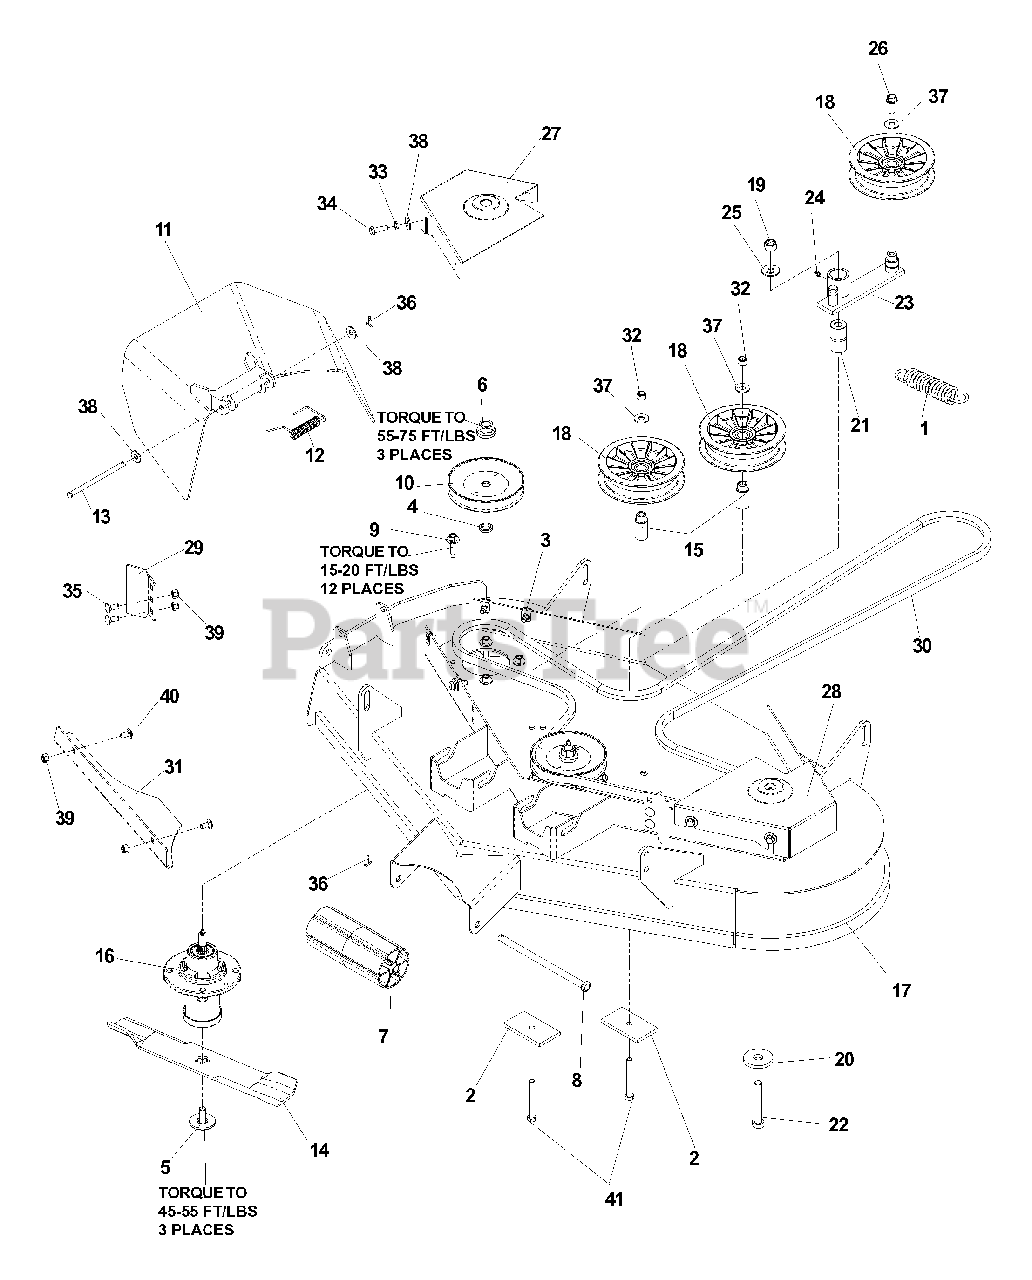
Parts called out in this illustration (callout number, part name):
1	SPRING, EXTENSION
2	PAD
3	NUT, 5/16-18, RETAINER-U TYPE
4	WASHER, .675 X .915 X .155, SPACER
5	BOLT, 7/16, SPEC
6	NUT, 9/16, CENTERLOCK, GR5
7	ROLLER, NOSE
8	ROD, ROLLER, NOSE, NARROW
9	SCREW, 5/16-18 X 1 3/8, WASH HD, SPEC
10	PULLEY, MANDREL
11	DISCHARGE CHUTE
12	SPRING, TORSION
13	PIN-CLEVIS, 5/16 DIA X 5.19
14	BLADE, 14.625"
15	IDLER BUSHING
16	HOUSING ASSEMBLY
17	DECK W/DECALS
18	IDLER PULLEY, NYLON
19	NUT, 1/2-13, NYLOC
20	WASHER, .65 X 2 X .25, SUPPORT
21	BUSHING, PIVOT
22	HCS, 1/2-13 X 3 1/4, GR5
24	ZERK, STRAIGHT, 1/4-28
25	WASHER, .562 X 1.38 X 14
26	HCS, 3/8-16 X 1, GR5, WHIZLK
27	BELTSHIELD, RIGHT
28	BELTSHIELD, LEFT
31	CONFINEMENT PLATE
32	NUT, 3/8-16, NYLOC
33	WASHER, 5/16
34	HCS, 5/16-18 X 1, GR5
35	RHSNB, 5/16-18 X 3/4, GR5
36	PIN COTTER, 1/8 X 3/4
37	WASHER, 3/8
38	WASHER, 5/16
39	NUT, 5/16-18, NYLOC
40	RHSNB, 5/16-18 X 5/8, GR5
41	HCS, 3/8-16 x 3, GR5
